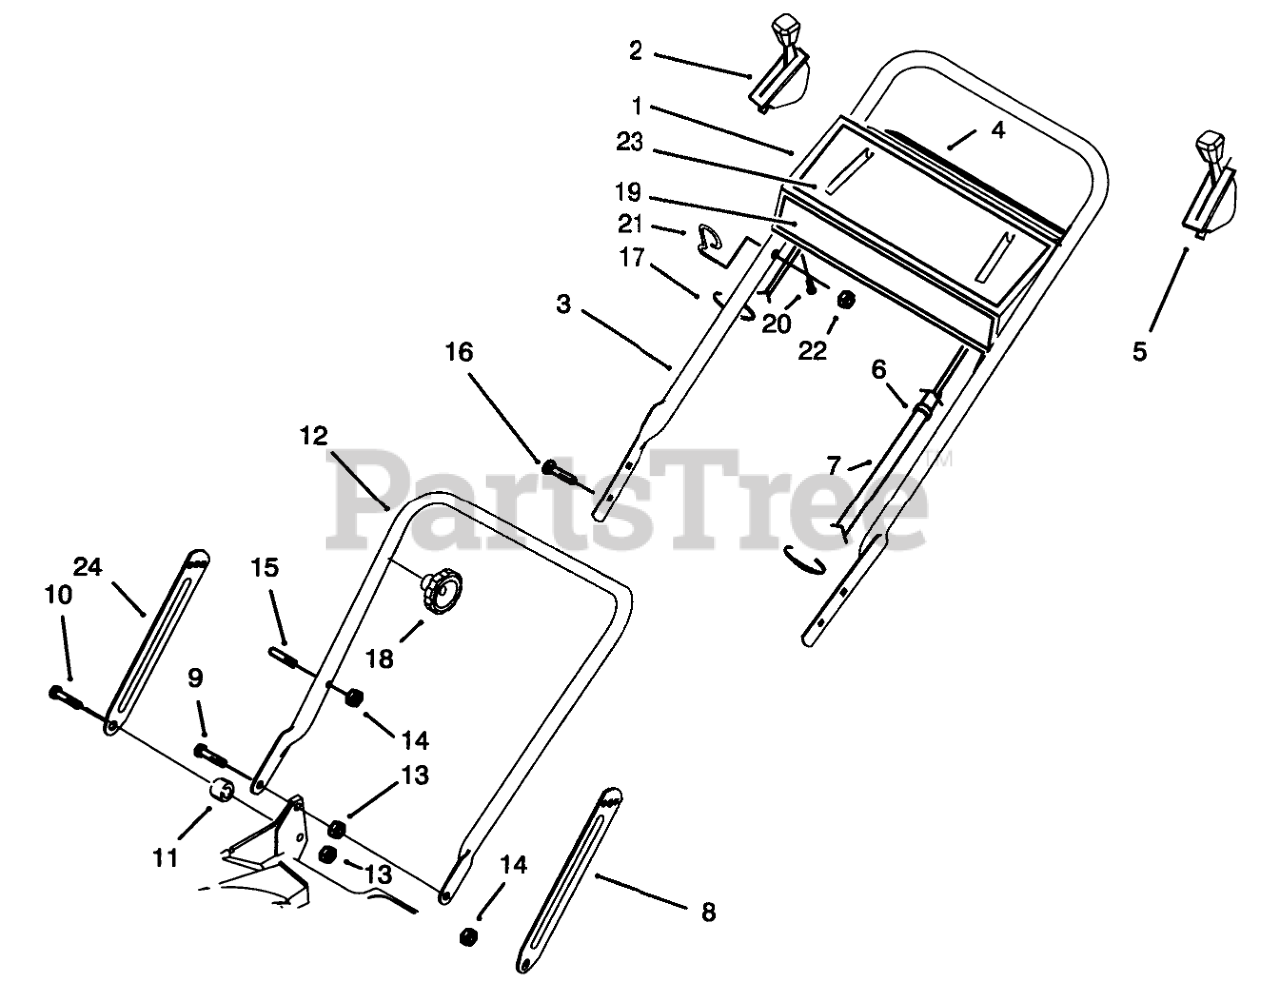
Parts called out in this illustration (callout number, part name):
1	Panel-Control (Incl. Ref. #4, 19, & 23)
2	CONTROL-SPEED, GROUND
3	Handle-Upper
4	DECAL - PANEL, REAR
5	THROTTLE CONTROL
6	FITTING-RING
7	CONTROL CABLE COVER
8	Latch-Handle
9	SCREW-SHOULDER
10	SCREW-SHOULDER
11	SPACER
12	LOWER HANDLE ASM
13	NUT-LOCK, NI
14	NUT-LOCK, NI
15	HANDLE PIN
16	SCREW-HANDLE
17	TIE-CABLE
19	DECAL - FRT PANEL
20	10-16X1/2 SHWH SCREW
21	GUIDE-ROPE
22	NUT-LOCK, NI
23	DECAL - INSTRUCTION
24	Latch-Handle
